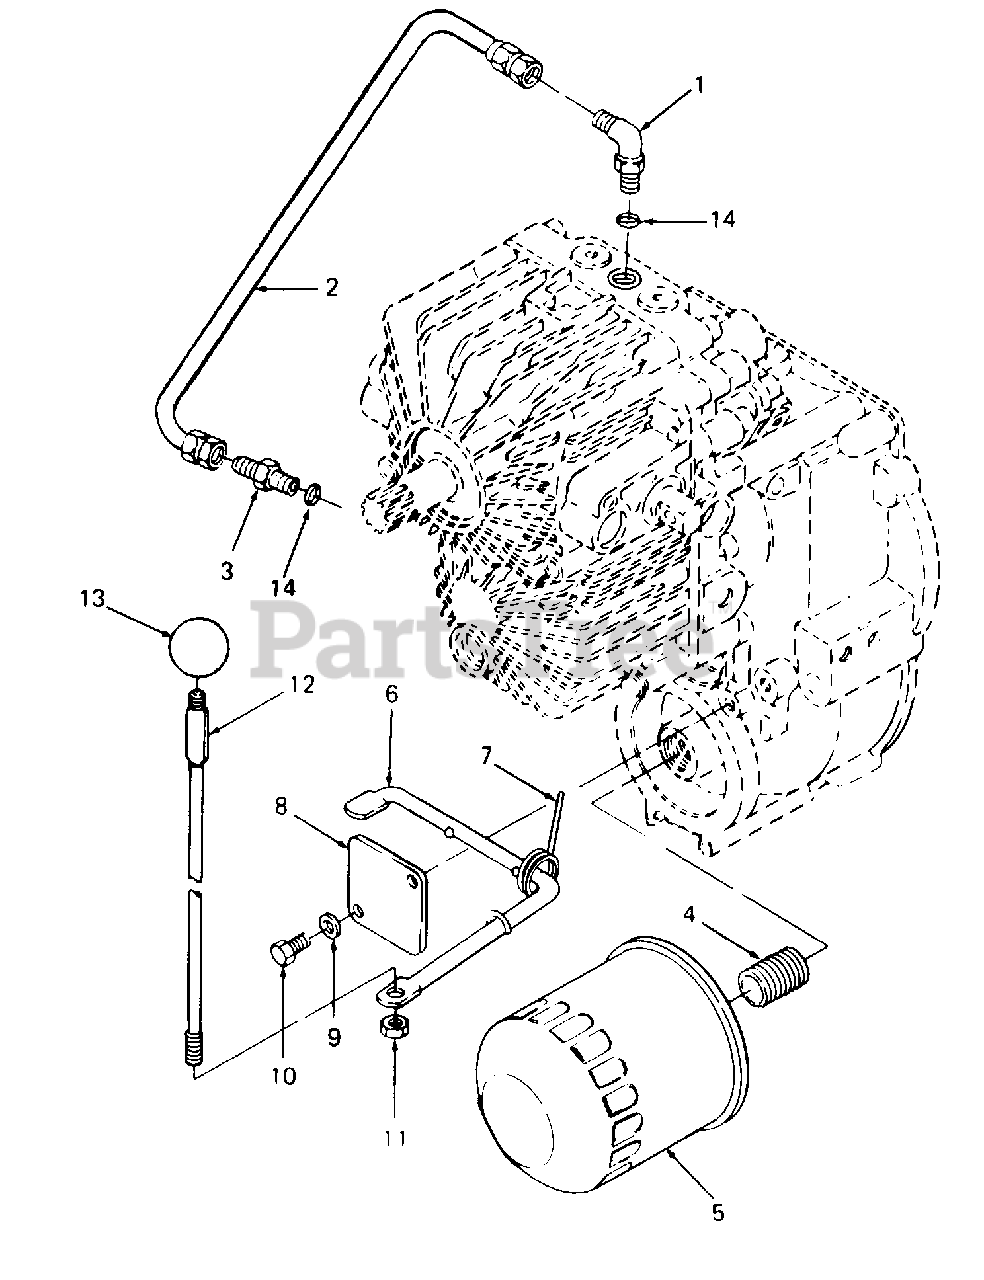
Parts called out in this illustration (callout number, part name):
1	Elbow, 90 Degree Tube
2	Line, Metal Pickup
3	Connector, 37 Degree Tube
4	Nipple, Oil Filter
5	Filter, Oil
6	Rod, Dump Valve Lower
7	Spring, Torsion
8	Plate, Retaining
9	Washer, Lock, 1/4
10	Screw, Hex Cap, 1/4-20 X .50 Lg GR5
11	Nut, Hex Top Lock, 1/4-20
12	Rod, Dump Valve Upper
13	Knob, Ball
14	O-Ring, 3/8 OD Tube
